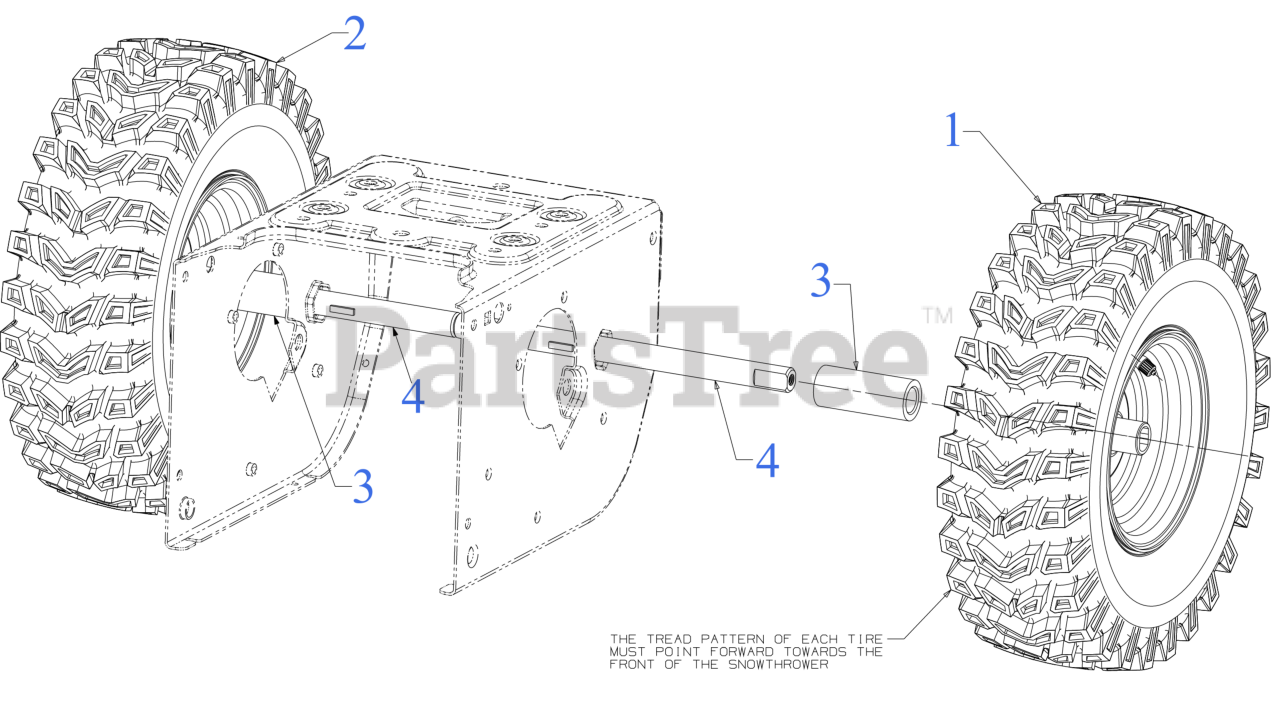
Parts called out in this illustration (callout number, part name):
1	WHL:COMPL:15X5.00-6 X-TRAC:LH
1	TUBELESS AIR VALVE
1	TIRE:X-TRAC:15X5.00-6
2	WHL:COMPL:15X5.00-6 X-TRAC:RH
2	TUBELESS AIR VALVE
2	TIRE:X-TRAC:15X5.00-6
3	WHEEL SPACER 1.25ODX.75X3.00
